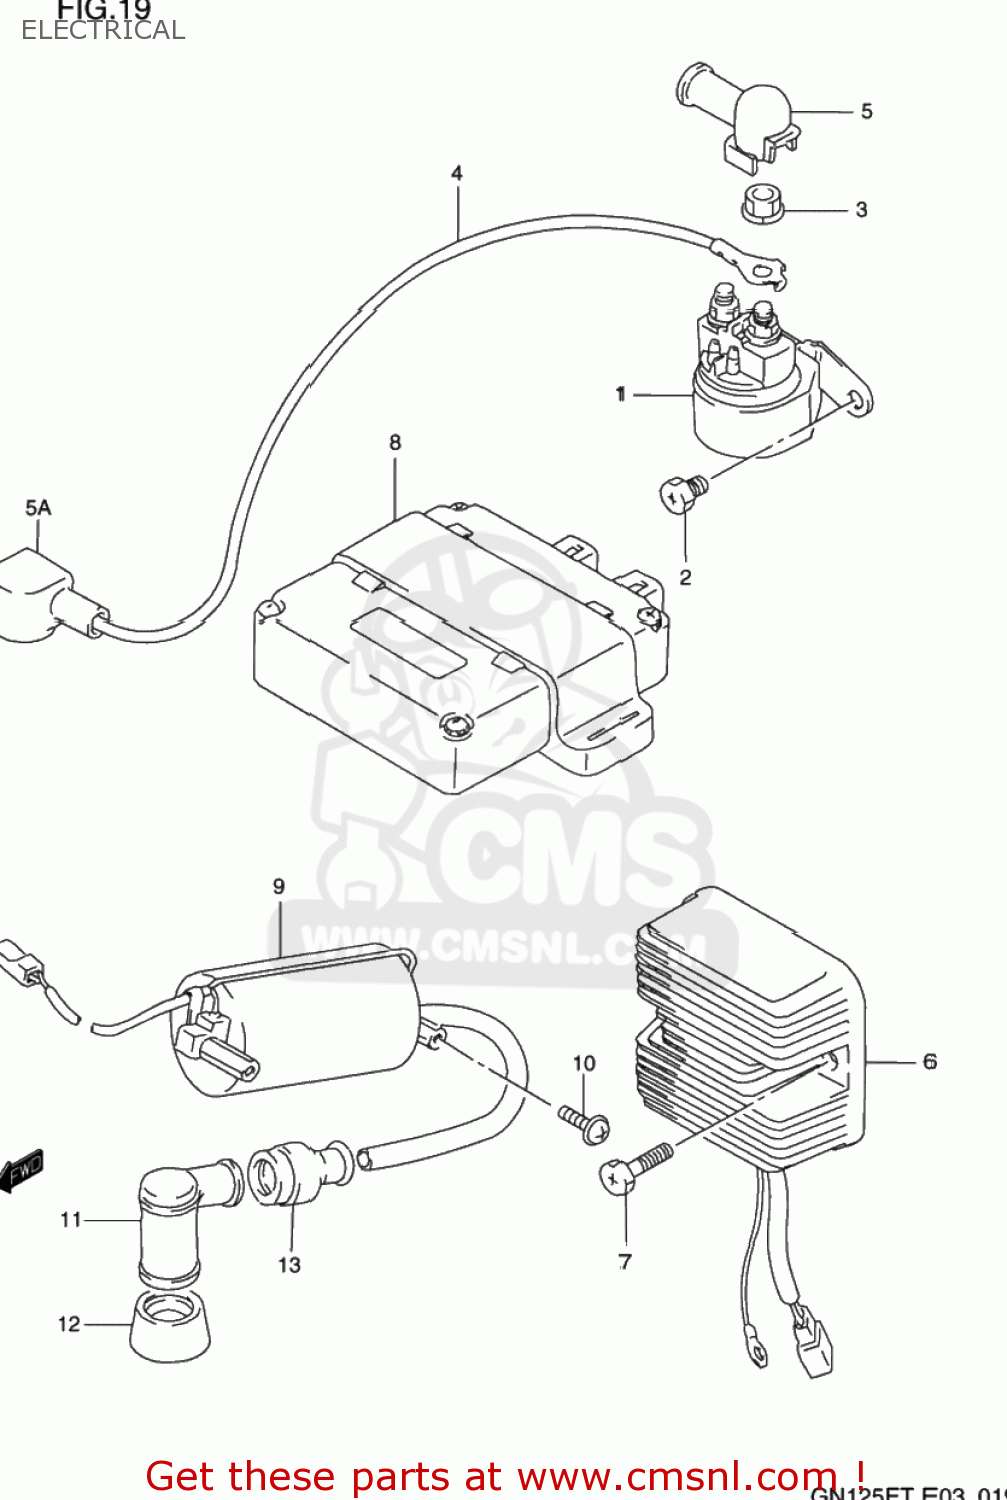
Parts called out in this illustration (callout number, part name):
1	RELAY ASSY,STARTING MOTOR
2	SCREW(6X10)
3	NUT
4	WIRE,STARTER MOTOR
5	CAP,TERMINAL
5A	CAP,STARTER MOTOR TERMINAL
6	RECTIFIER ASSY
7	BOLT(6X20)
8	IGNITOR UNIT
9	COIL ASSY,IGNITION
10	SCREW
11	CAP ASSY,SPARK PLUG
12	SEAL,SPARK PLUG CAP
13	SEAL,HIGH TENSION CORD
